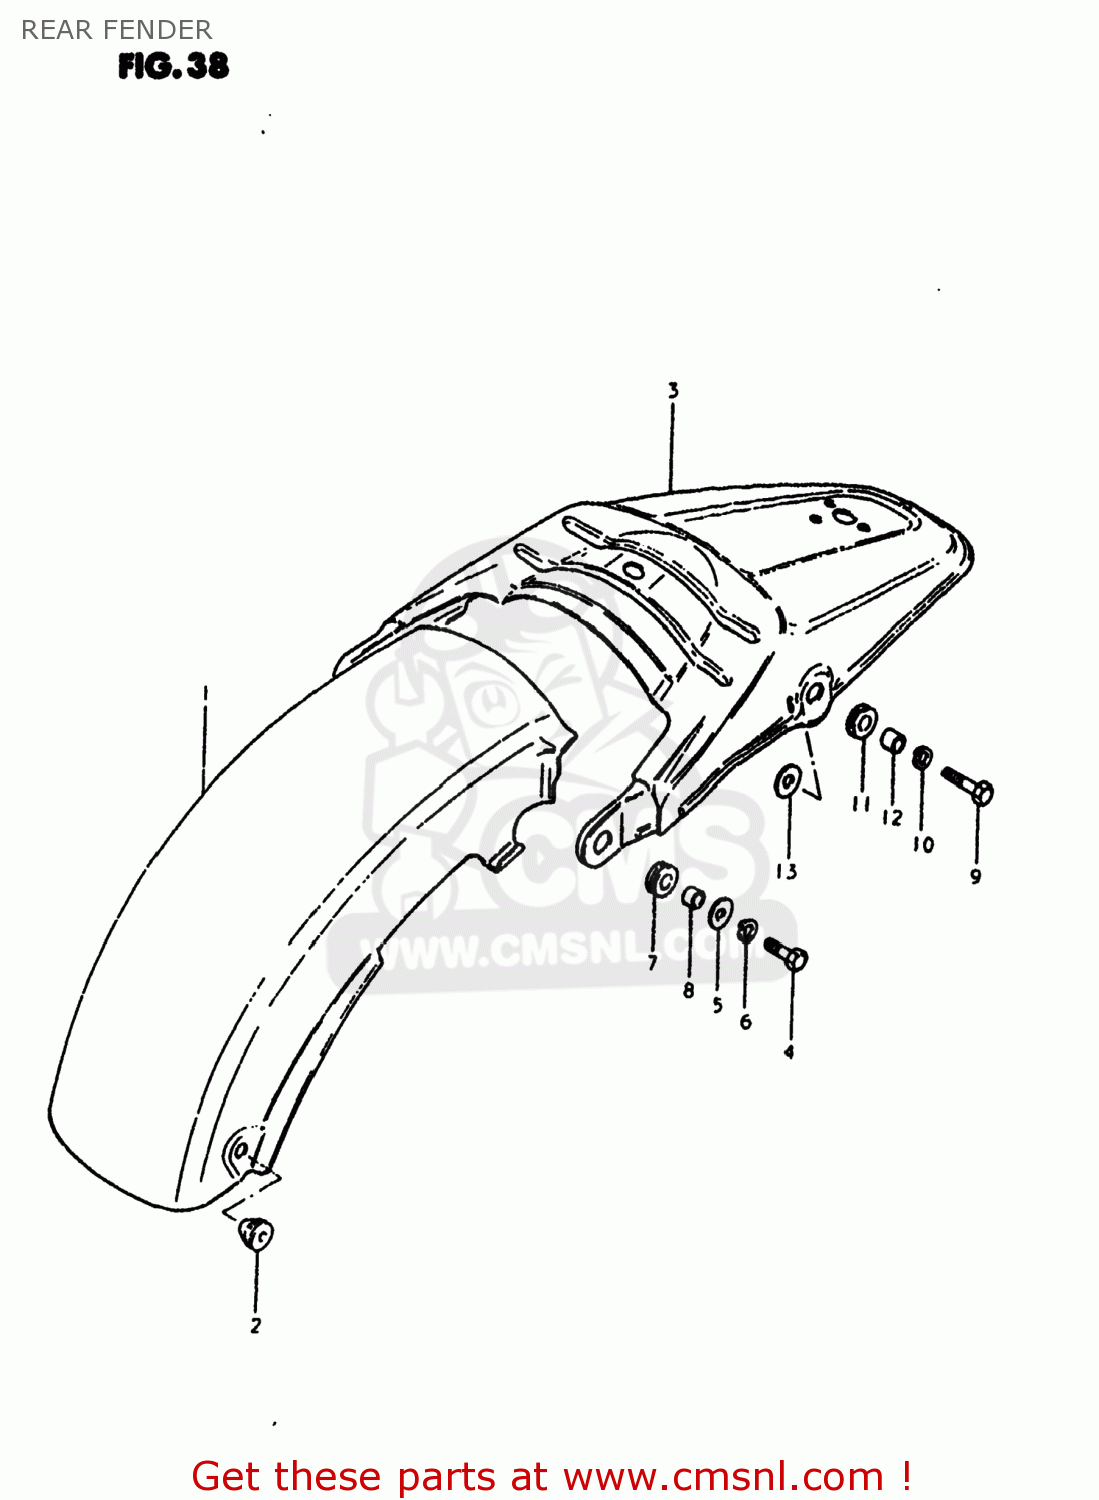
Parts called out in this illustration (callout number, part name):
1	FENDER,REAR
2	CUSHION,REAR FENDER,FRONT
3	FENDER,REAR
4	BOLT
5	WASHER (6.5X20X1.2)
6	LOCK WASHER
7	CUSHION
8	SPACER(6.1X9X7.5)
9	BOLT
10	LOCK WASHER
11	CUSHION
12	SPACER(8.2X10X8)
13	WASHER (8.2X24X1.6)
